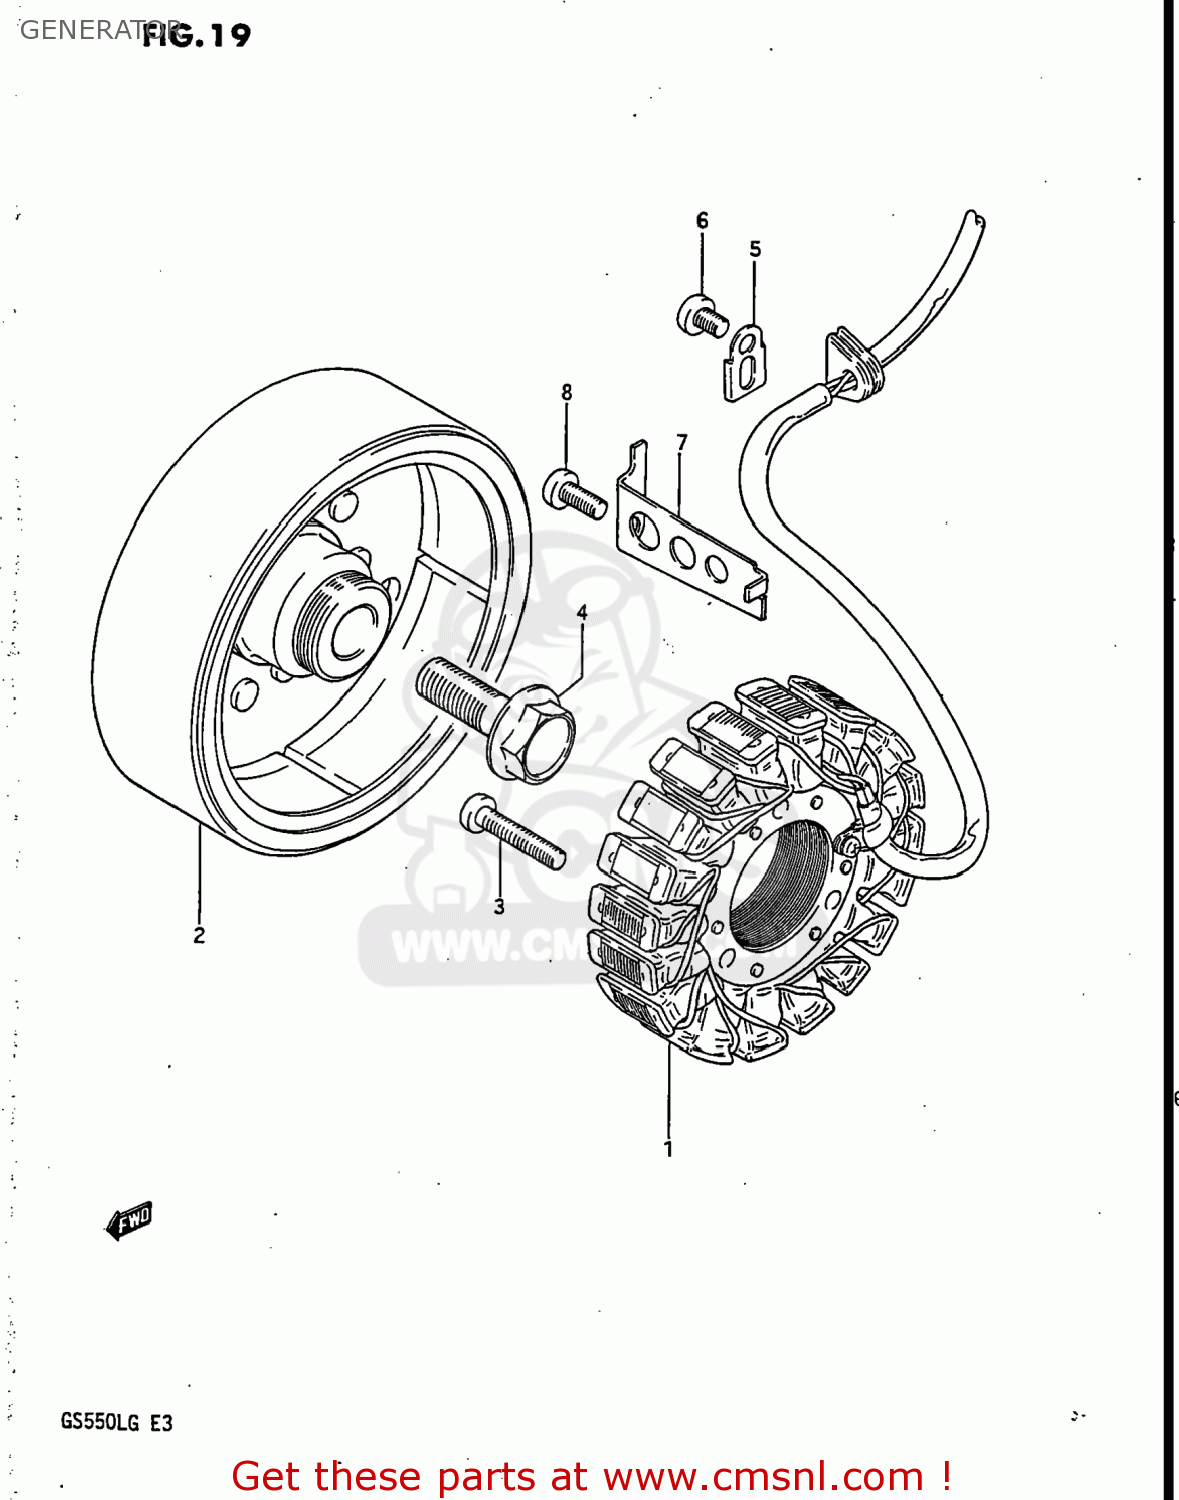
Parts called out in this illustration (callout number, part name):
1	STARTER ASSY
2	ROTOR ASSEMBLY
3	SCREW 6X30
4	BOLT(14X43)
5	CLAMP,GENERATOR LEAD WIRE
6	SCREW
7	CLAMP,GENERATOR LEAD WIRE
8	SCREW
